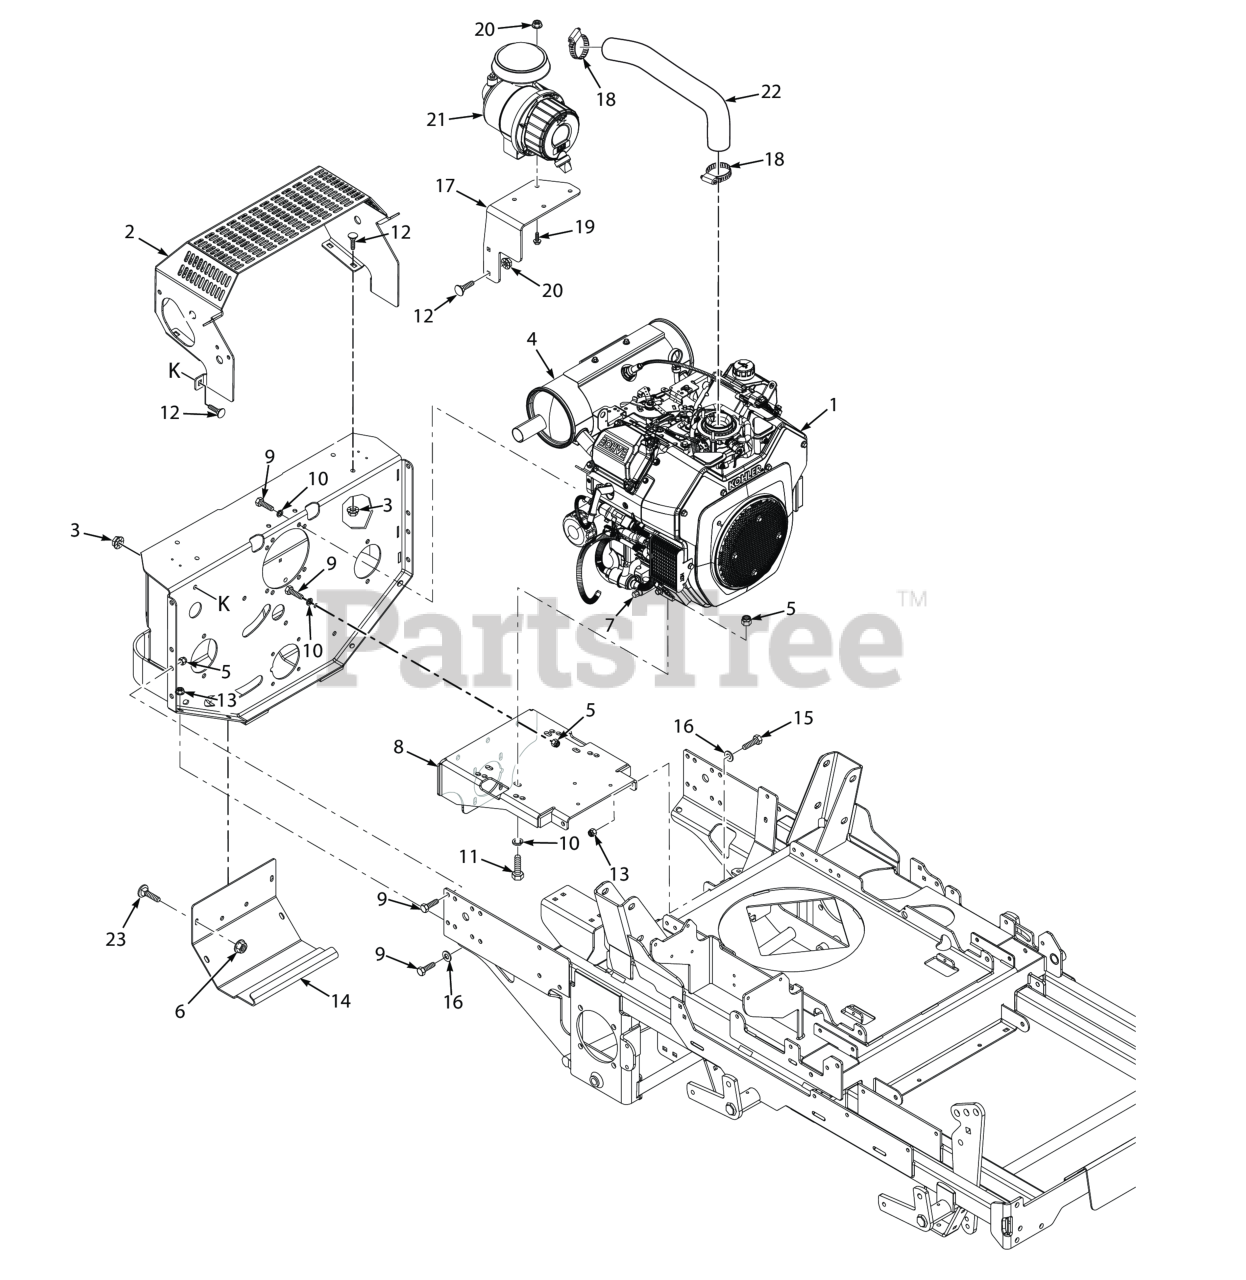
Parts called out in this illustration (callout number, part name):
1	Engine, 25 LP-EFI - Kohler
2	Guard, Muffler
3	Nut, Flange Head Elastic Stop 5/16-18
4	Muffler, 25 LP-EFI - Kohler
5	HEX NUT, ELASTIC STOP LOCK, 3/8-16
6	Nut, Serrated Flange 5/16-18 (Right Front Engine Mounting, Briggs and Kohler Only)
7	Oil Drain, Kohler 25 LP-EFI
8	Plate Weldment, Engine Mounting
9	Bolt, Hex Head, 3/8-16 x 1 Gr. 5
10	Lockwasher, 3/8" Spring, Kawasaki FX / FS
11	Bolt, Hex Head 3/8-16 x 1-3/4" (Kohler EFI)
12	Bolt, 5/16-18 x .75 RHSN Carriage
13	Nut, Flange Elastic Stop Nut, 3/8-16
14	Cover, Rear
15	Bolt, Hex Head 3/8-16 x 1-1/4", Kawasaki FX / FS
16	Flatwasher, 3/8" Special (.391 x .938 x .105)
17	Bracket, Air Cleaner Mount
18	Clamp, 2-3/4" Max. Dia.
19	Cpscrw, 5/16-18 x 1"Serrated Flange Hex Head
20	Nut, Serrated Flange 5/16-18 (Right Front Engine Mounting, Briggs and Kohler Only)
21	Air Filter Assembly
22	Hose, Air Intake
23	Bolt, Carriage 1/4-20 x 1/2"
